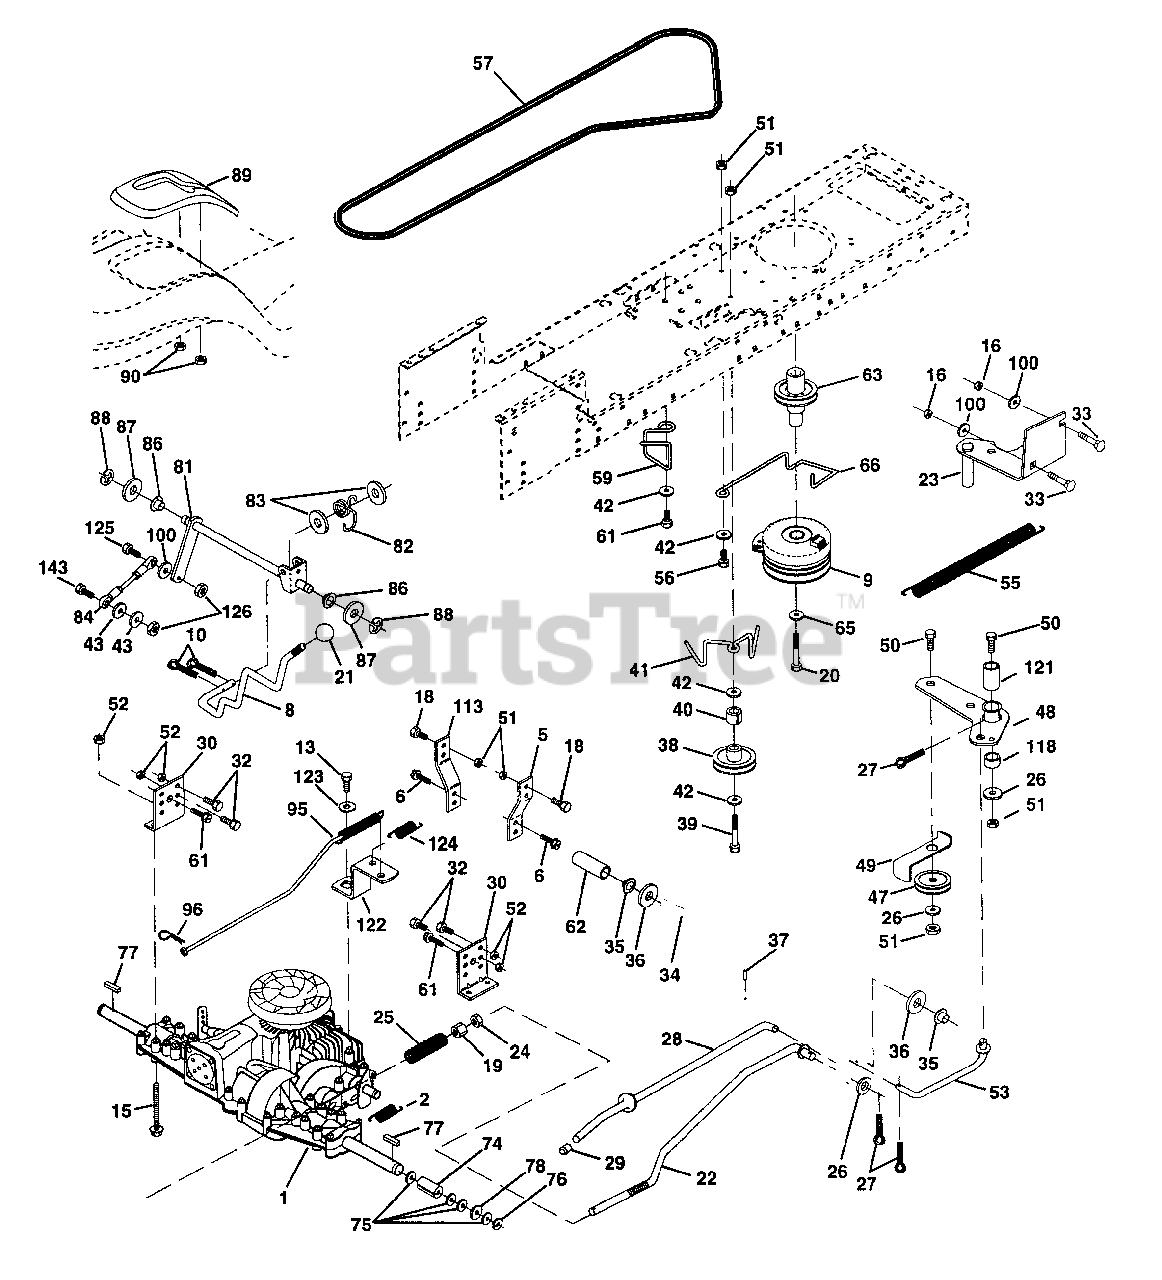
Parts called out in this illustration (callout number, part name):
1	Transaxle
2	Spring, Return Brake
5	Strap Torque
6	Screw Thdrol 5/16-18 x 3/4
8	Rod Shift Fender STLT
9	Clutch Elec Evx
10	Pin Cotter 1/8 x 1 CAD
13	Bolt 1/4-28 Unf Gr. 8 W/Patch
15	Bolt Hex Flghd 5/16-18 Gr. 5
18	Bolt Fin Hex 3/8-16 Unc x 1 Gr. 5
19	Nut Lock Hex W/Wsh 3/8-16 Unc
20	Bolt Hex 7/16-20 x 4-1/4
21	Knob, Deluxe 1 /2-13
22	Rod, Brake
23	Bracket Asm Clutch Mtg Evx
24	Nut, Hex Jam 3/8-16 Unc
25	Spring, Brake Rod
26	Washer
27	Pin Cotter 1/8 x 3/4 CAD.
28	Rod, Parking Brake
29	Cap, Parking Brake
30	Bracket, Transaxle
32	Bolt Hex Hd 5/16-18 Unc x 3/4
33	Bolt Rdhd Sqnk 5/16-18 UNC x 3/4
34	Shaft, Foot Pedal
35	Bearing, Nylon
37	Pin, Roll
38	Pulley, Idler, Flat
40	Spacer, Split
41	Keeper, Belt, Idler
42	Washer 13/32 x 13/16 x 12 Gauge
43	Washer 11/32 x 5/8 x 12 Ga.
47	Pulley, Idler, V-Groove
48	Bellcrank Assembly
49	Retainer, Belt
50	Bolt
51	Nut Crownlock 3/8-16 UNC
52	Nut, Crownlock 5/16-18 Unc
53	Link, Clutch
55	Spring, Return, Clutch
56	Bolt Hex 3/8-16 x 1-1/4
57	V-Belt, Ground Drive
59	Keeper, Center Span
61	Screw Thdrol. 3/8-16 x 3/4 Ty. TT
62	Cover, Pedal
63	Pulley, Clutch Elec
65	Washer
66	Keeper Belt Engine
74	Spacer, Axle PVST
75	Washer 25/32 x 1-1/4 x 16 Gauge
77	Key, Square
78	Washer 25/32 x 1-5/8 x 16 Gauge
81	Shaft Asm. Cross Hydro 20" Tires
82	Spring Torsion T/A
83	Washer 17/32 x 3/4 x 16 Ga.
84	Rod, Tie PVST 20"
86	Bushing Rod Strig. 629/632 ID
87	Washer 21/32 x 1-1/4 x 16 Ga.
88	Ring Klip #5304-62
89	Console, Shift
90	Nut Self-Thd Wsh-Hd 1/4 Zinc
95	Rod Asm Bypass PVST
96	Retainer Spring 1" Zinc/Cad
100	Washer 11/32 x 3/4 x 16 Ga.
113	Strap Torque LH LT
116	Bolt Rdhd Sq. Neck 3/8-16 x 1.25
118	Spacer Bellcrank
121	Nyliner Clutching STL
122	Plate Bypass PVST
123	Washer 9/32 x 5/8 x 16 Ga.
124	Spring Return PVST
125	Bolt Fin Hex 5/16-18 Unc x 1
126	Nut Lock 5/16-18 Unc
143	Bolt Hex Fin 5/16-18 UNC x 1-1/4
